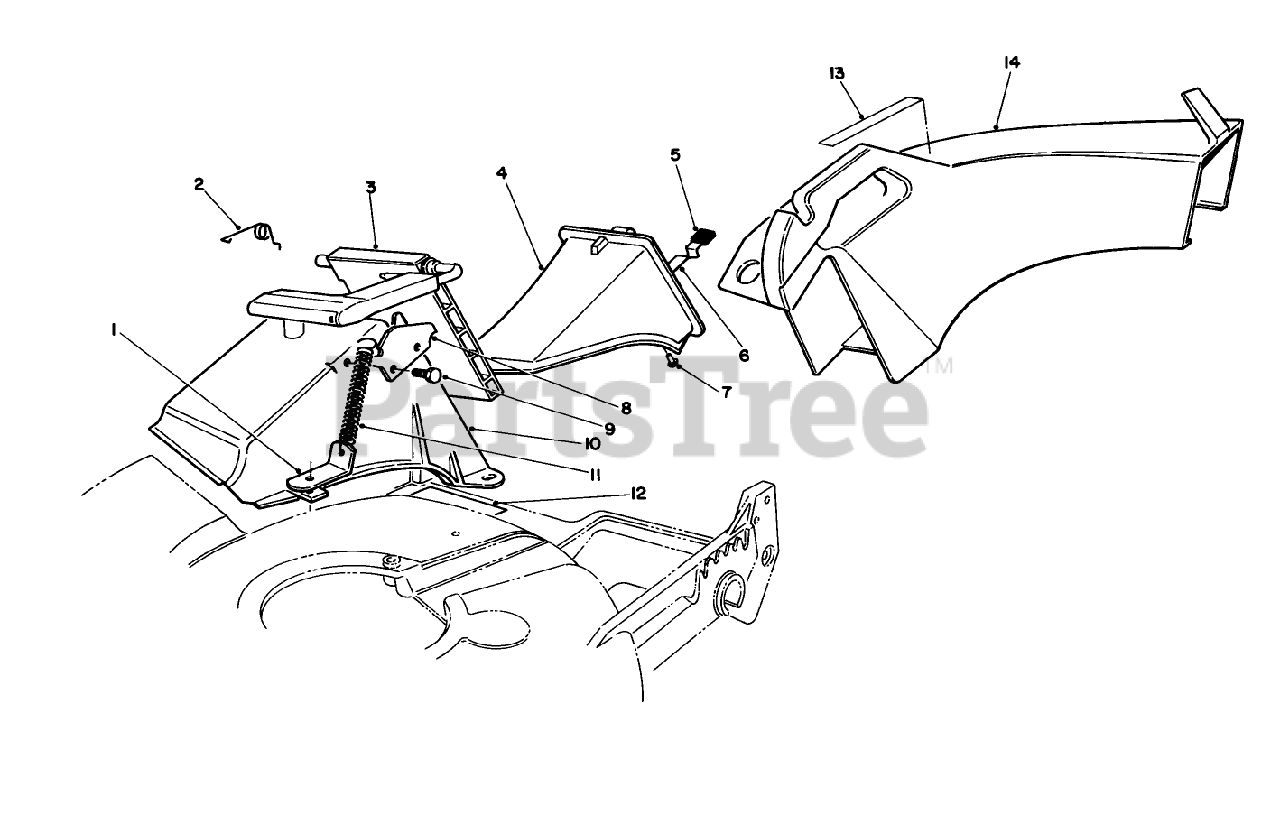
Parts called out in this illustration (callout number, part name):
1	BRACKET-SPRING
2	RETAINER-DOOR
4	DISCHARGE PLUG ASM
5	GRIP-LATCH
6	LATCH-PLUG, DISCHARGE
7	RIVET-HEAD, FLAT
8	DOOR LATCH PLATE
9	SCREW-PLASTITE
10	DISCHARGE TUNNEL
11	SPRING-DOOR
13	DECAL - WARNING
14	Chute-Discharge (Incl. Ref. #13)
